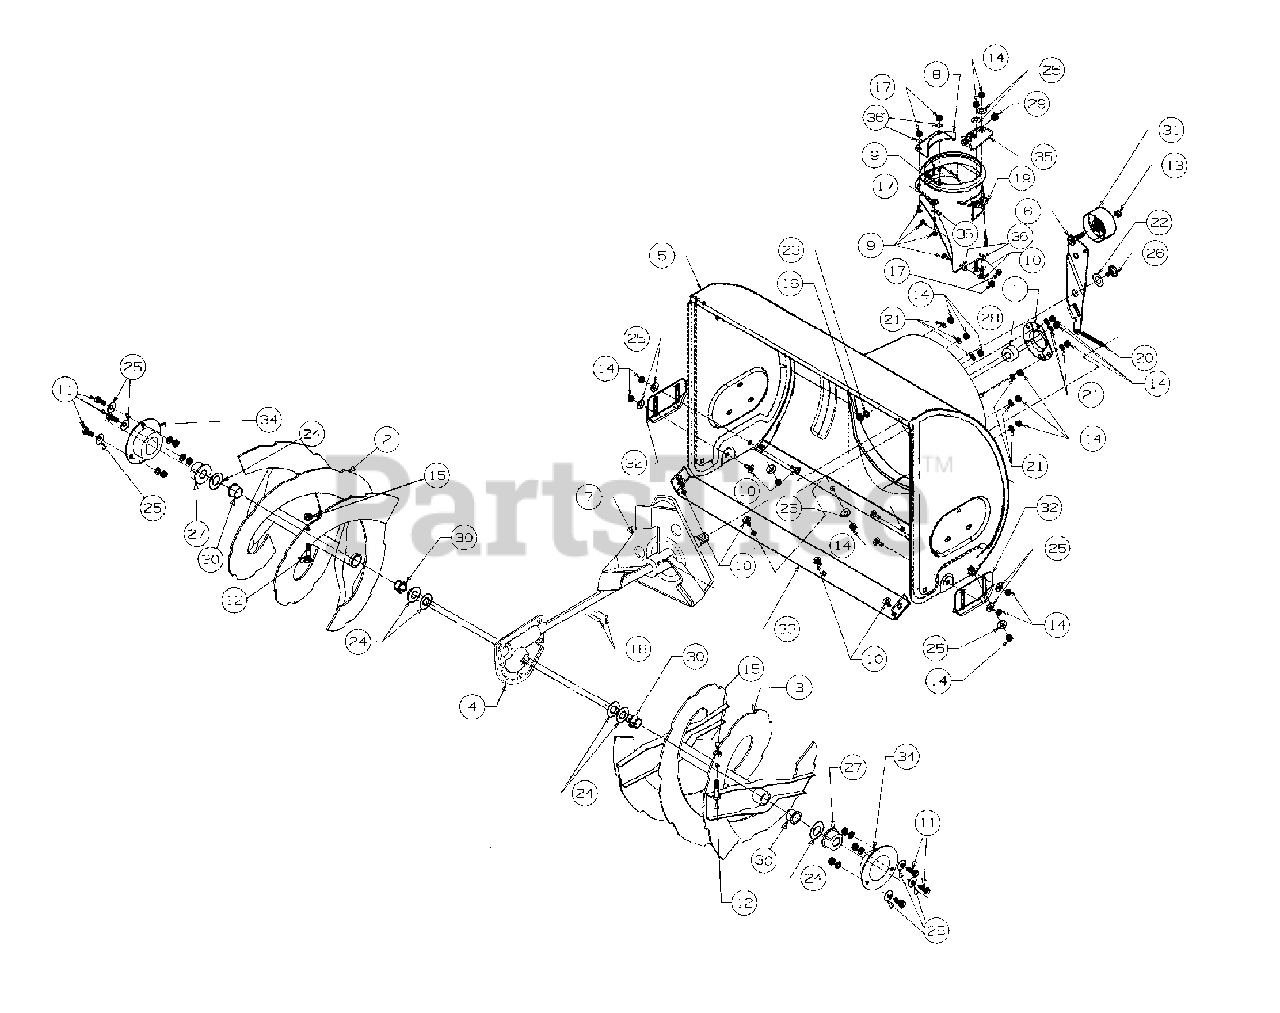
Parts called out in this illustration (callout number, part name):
1	Housing - Bearing
9	Screw - Carriage
10	Screw - Carriage
11	Screw - Hex
12	Shear Bolt
13	Nut - Hex Lock
14	Nut - Hex
15	Nut - Hex
16	Nut - Hex
17	Nut - Hex Lock
18	Pin - Spring
19	Adapter - Chute
20	Spring
21	Washer - Lock
22	Washer - Wave
23	Washer - Lock
24	Washer - Flat
25	Washer - Bell
26	Screw - Shoulder
27	Bearing - Flange
28	Bearing - Ball
29	Bushing - Plastic
30	Bushing - Flange
31	Idler - Flat
36	Flat Washer
